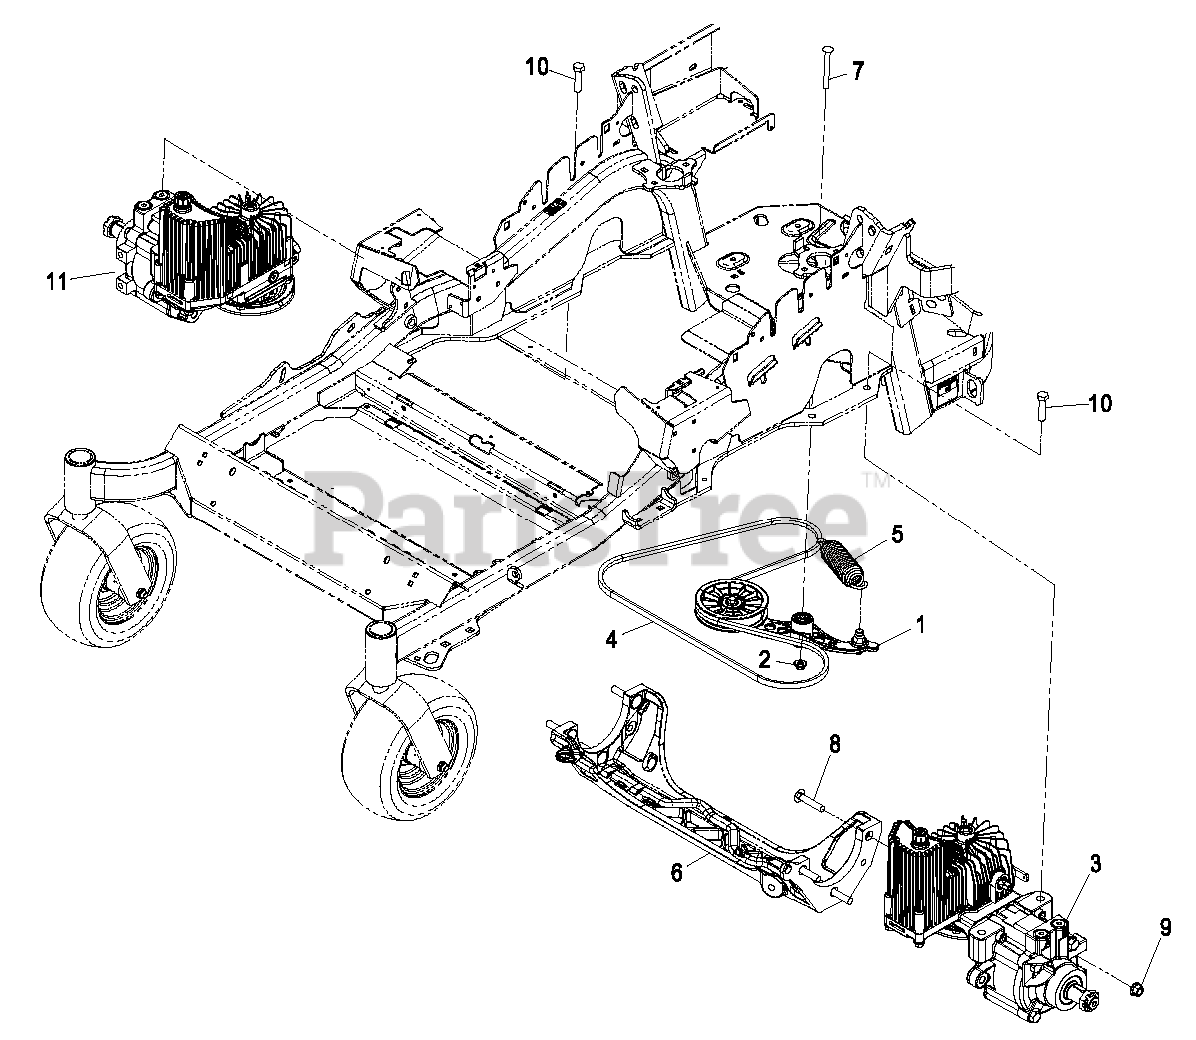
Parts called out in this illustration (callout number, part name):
1	PUMP IDLER ASM
2	Nut-Nyloc 3/8-16 Flg
4	BELT-V
7	BOLT-SHOULDER, CARRIAGE 3/8-16 X 3 1/2
8	SCREW-CARR
9	Nut-Lock 1/2-13
10	SCREW-HH
